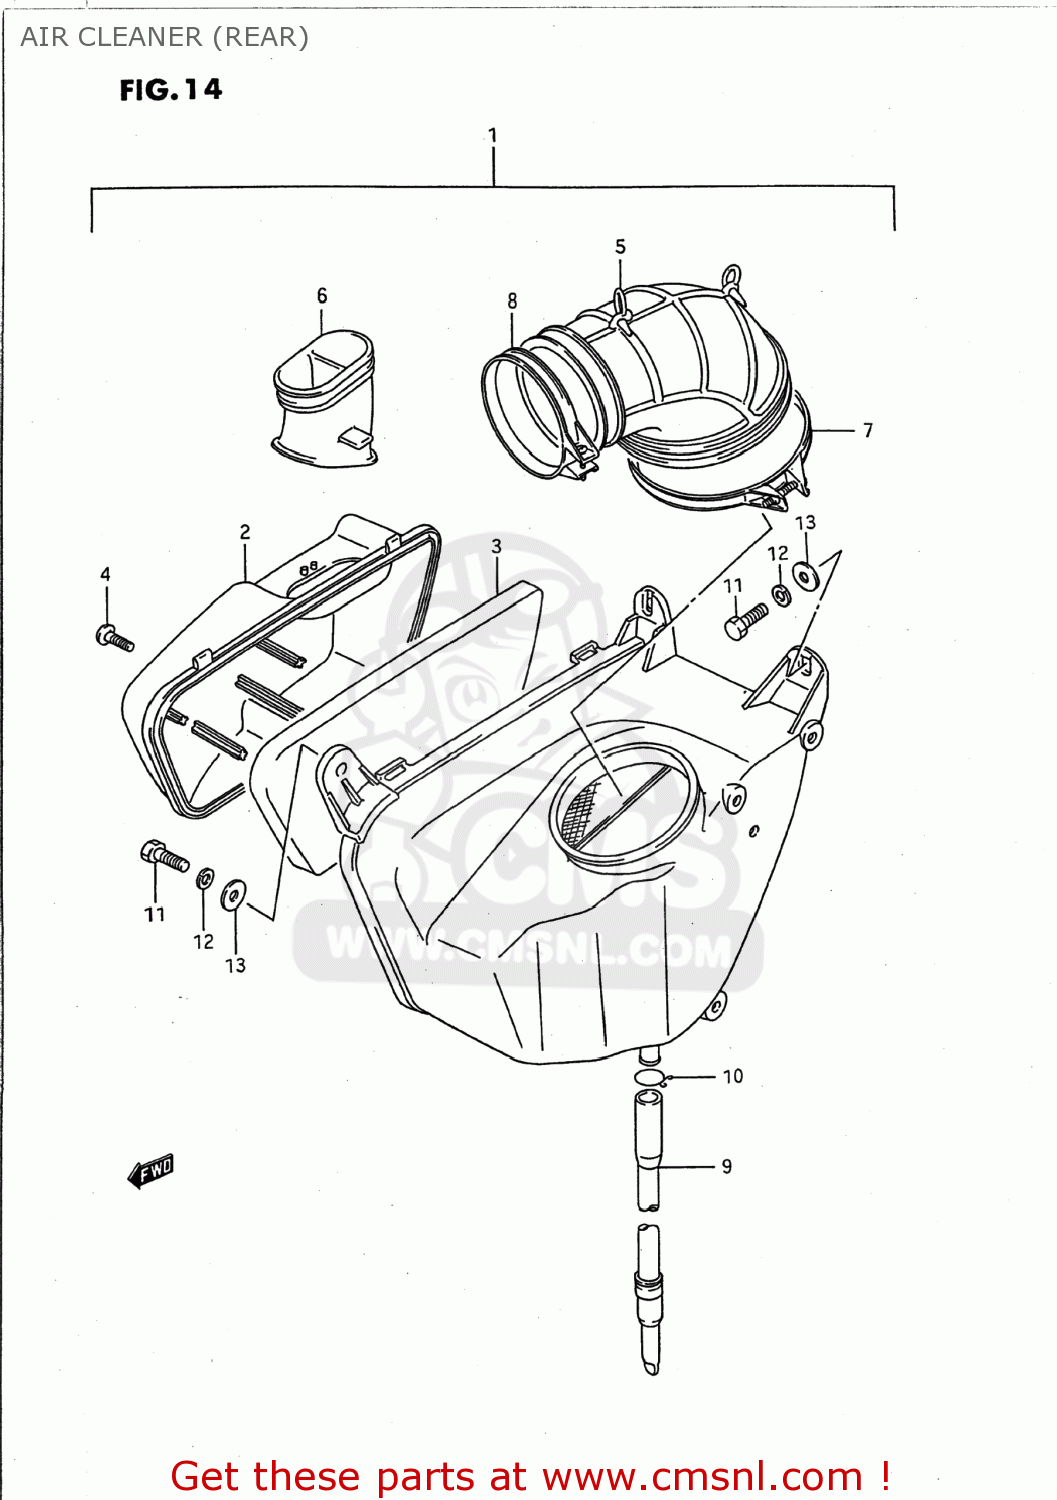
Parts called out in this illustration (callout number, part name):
1	CLEANER ASSEMBLY,AIR
2	CAP,AIR CLEANER
3	FILTER,AIR RR
4	SCREW
5	TUBE,AIR CLEANER OUTLET
6	TUBE,INLET
7	CLAMP
8	CLAMP
9	DRAIN TUBE
10	CLIP
11	BOLT
12	WASHER,LOCK
13	WASHER(6.5X16X1.2)
